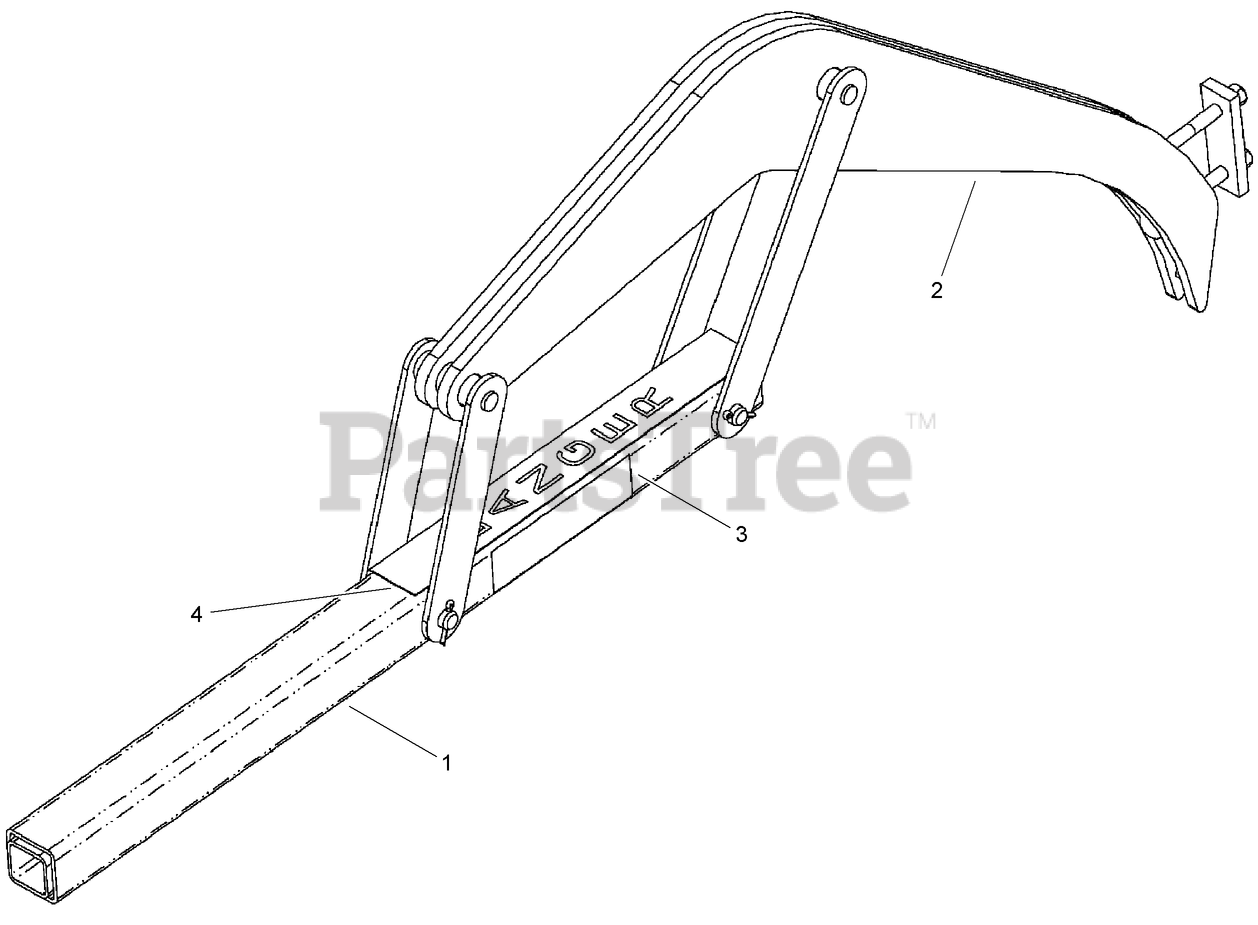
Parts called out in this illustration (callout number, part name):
1	BOOM-crumber, 4 foot, heavy duty planetary trencher
2	I / BASIC CRUMBER ASM
3	DECAL-Danger, Entanglement Hazard
4	DECAL-Danger
